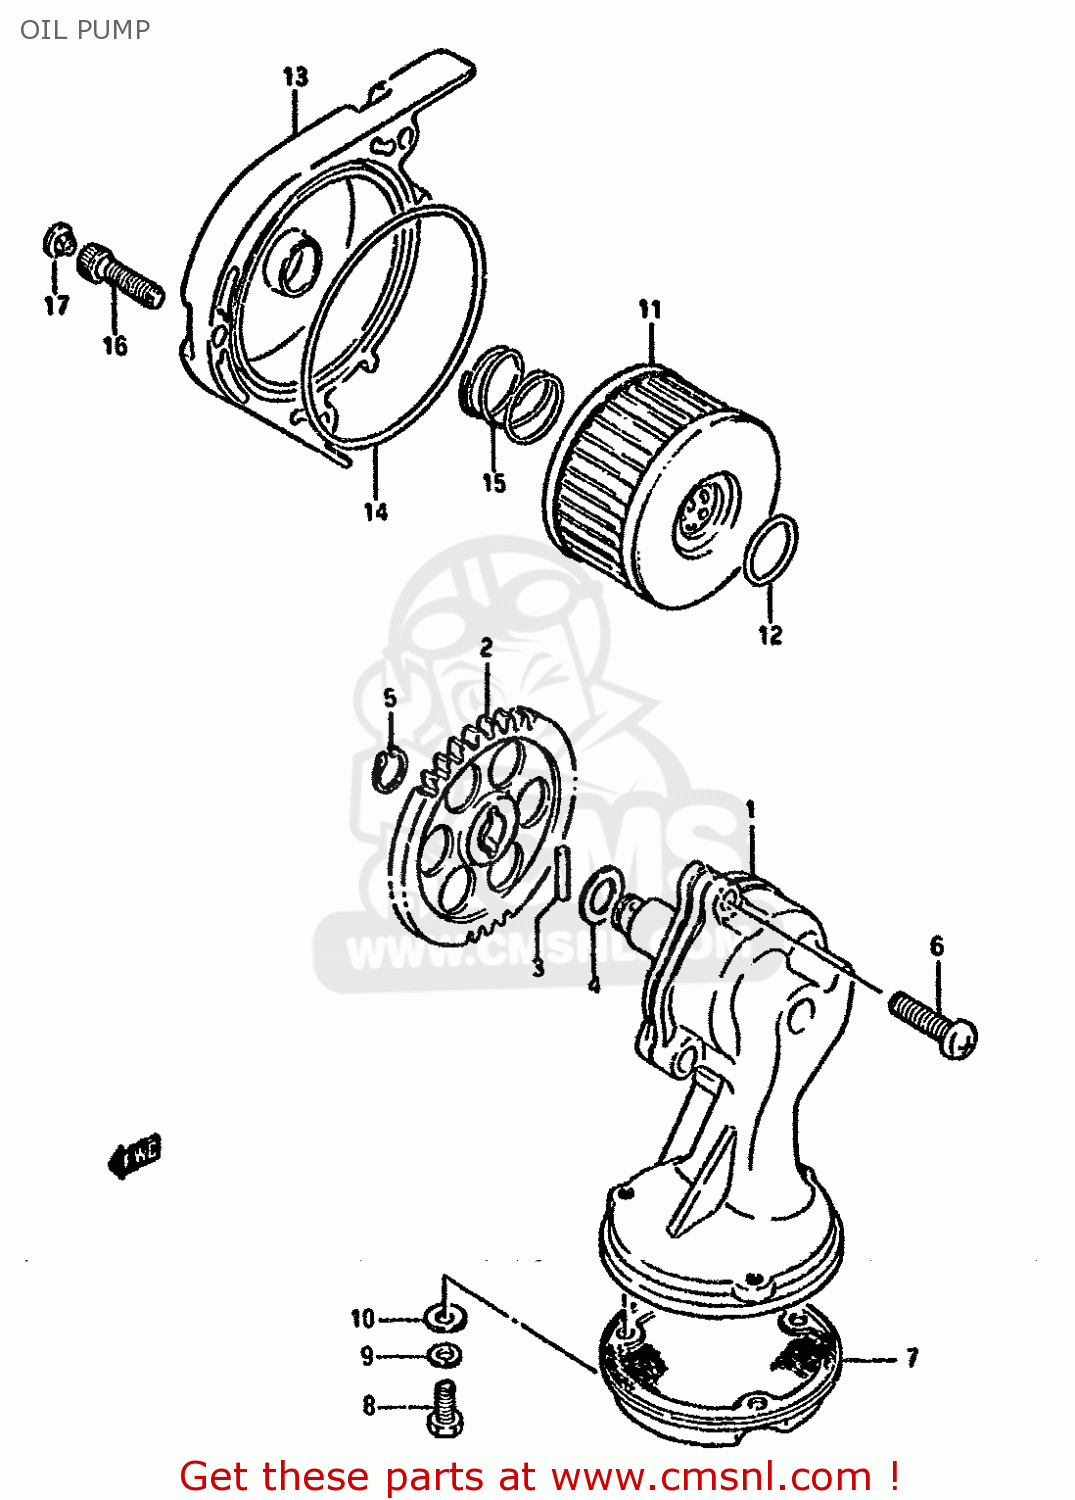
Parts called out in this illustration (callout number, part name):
1	PUMP ASSY,ENGINE OIL
2	GEAR,ENG OIL PUMP DRIVEN
3	PIN(4X15.8)
4	SHIM
5	CIRCLIP,10MM
6	SCREW
7	STRAINER,ENGINE OIL
8	BOLT 5X12
9	LOCK WASHER
10	WASHER
11	FILTER,ENGINE OIL
12	O RING(D:2.4,ID:15.8)
13	CAP,OIL FILTER
14	O RING(D:2.4,ID:73)
15	SPRING
16	BOLT
17	CAP(OD:10)
